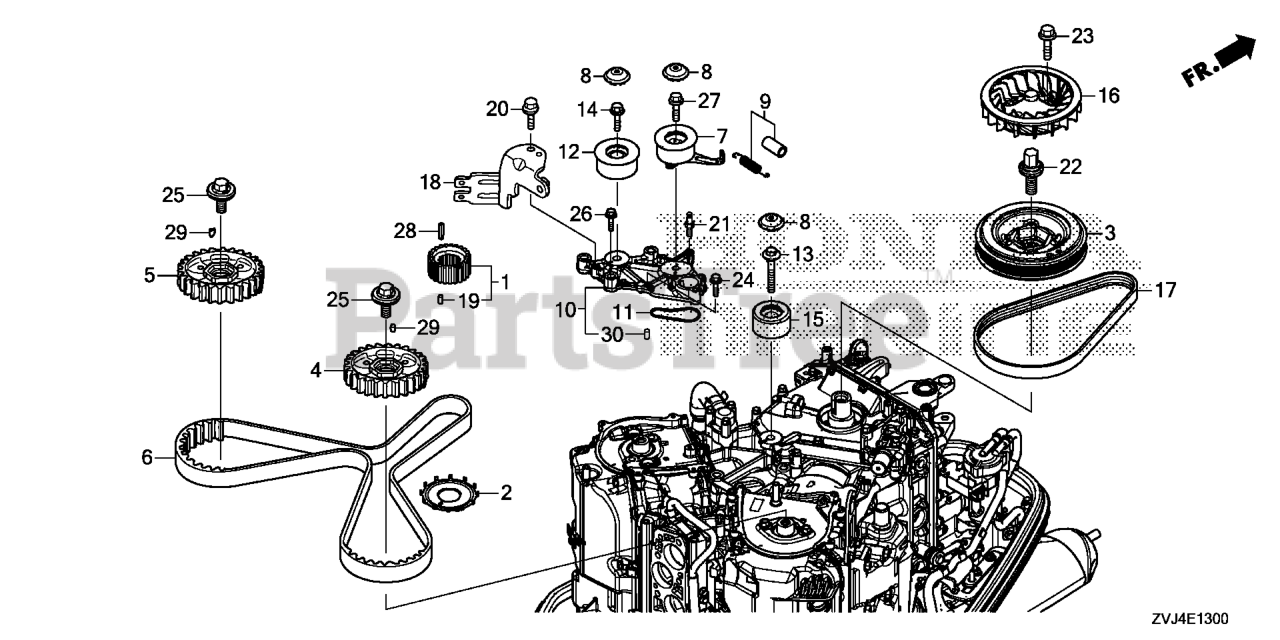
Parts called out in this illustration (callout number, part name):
1	PULLEY, TIMING BELT DRIVE
2	PLATE, CRANK PULSER
3	PULLEY, CRANKSHAFT
4	PULLEY, R. TIMING BELT DRIVEN
5	PULLEY COMP
6	BELT, TIMING (197YU26 GB-323)
7	TENSIONER, TIMING BELT
7	TENSIONER COMP, T/B
8	CAP, TIMING BELT TENSIONER
9	SPRING, TIMING BELT ADJUSTING
10	BASE, TIMING BELT TENSIONER *NH8* (DARK GRAY)
11	O-RING, TIMING BELT TENSIONER BASE
12	IDLER, TIMING BELT (KOYO SEIKO)
13	BOLT, IDLER
14	BOLT, TIMING BELT IDLER
14	BOLT, T/B IDLER
15	IDLER B, TIMING BELT
16	FAN, COOLING
17	BELT, ALTERNATOR (6PK745 M-180)
18	BRACKET, CONNECTOR D
19	PIN, VERTICAL SHAFT
20	BOLT, FLANGE (6X14) (CT200)
21	BOLT, T/B ADJ SPG
22	BOLT-WASHER (16X49)
23	BOLT, FLANGE (6X16)
24	BOLT, FLANGE (6X22)
25	BOLT-WASHER (12X35)
26	BOLT, FLANGE (10X40)
27	BOLT, FLANGE (10X43)
28	KEY (4.5X24)
29	KEY, SPECIAL
30	PIN A, DOWEL (6X10)
